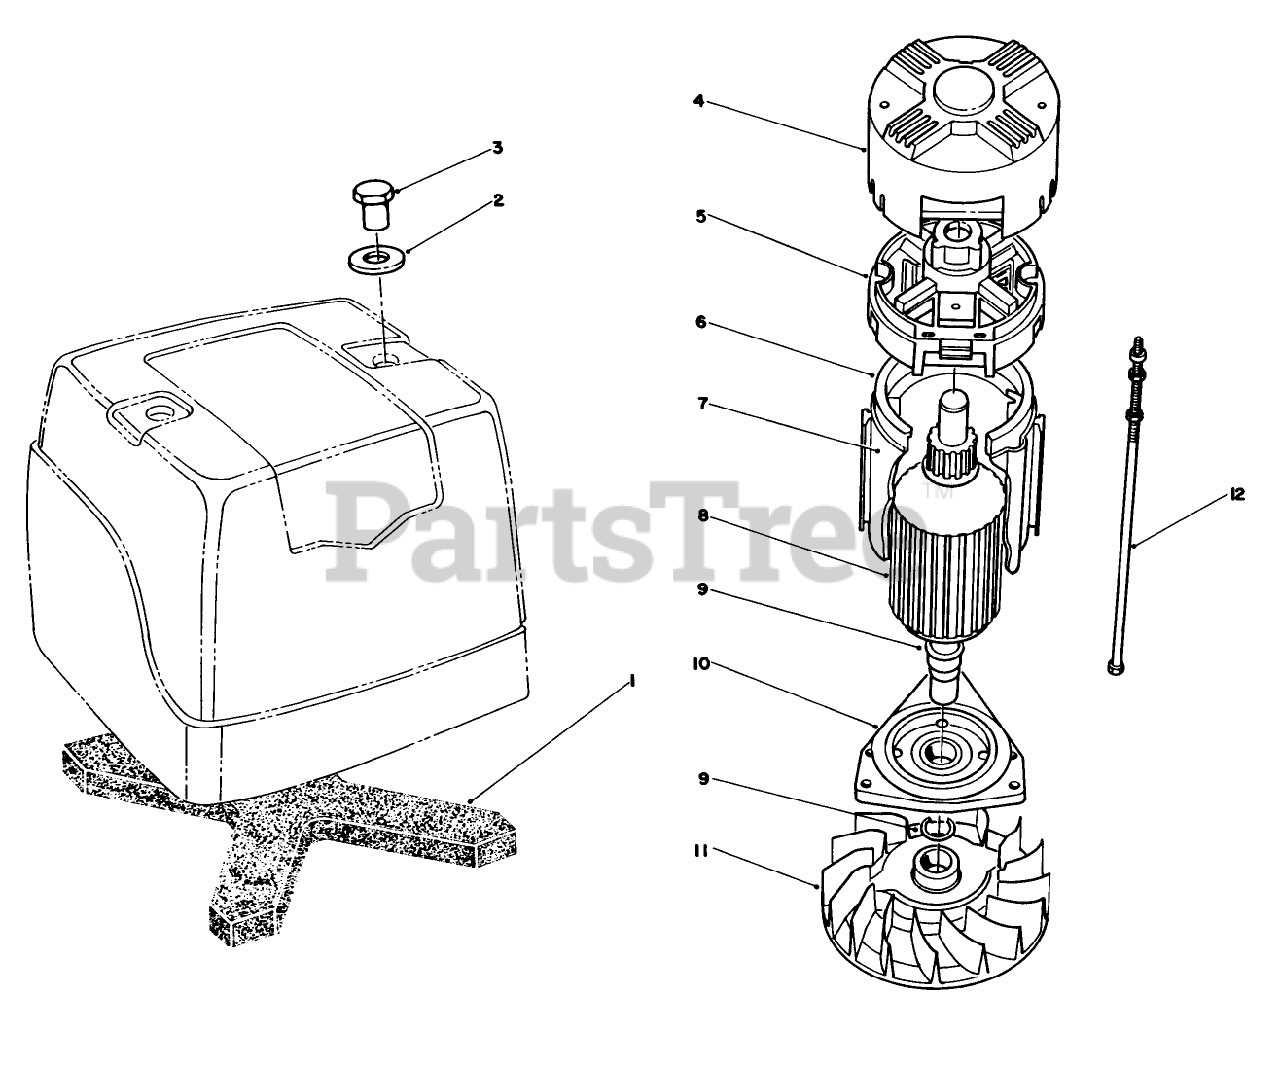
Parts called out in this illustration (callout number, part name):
1	Filter
2	Washer
3	Nut-Hex
4	End Cap-Brush
5	Brush Box Group (Includes: 490834 Brush Pin Group)
6	Housing Assembly
7	Insulator Group-Housing
8	Armature Group
9	Ring-Retaining
10	Spacer
12	Bolt-Thru (Includes Two Sets)
